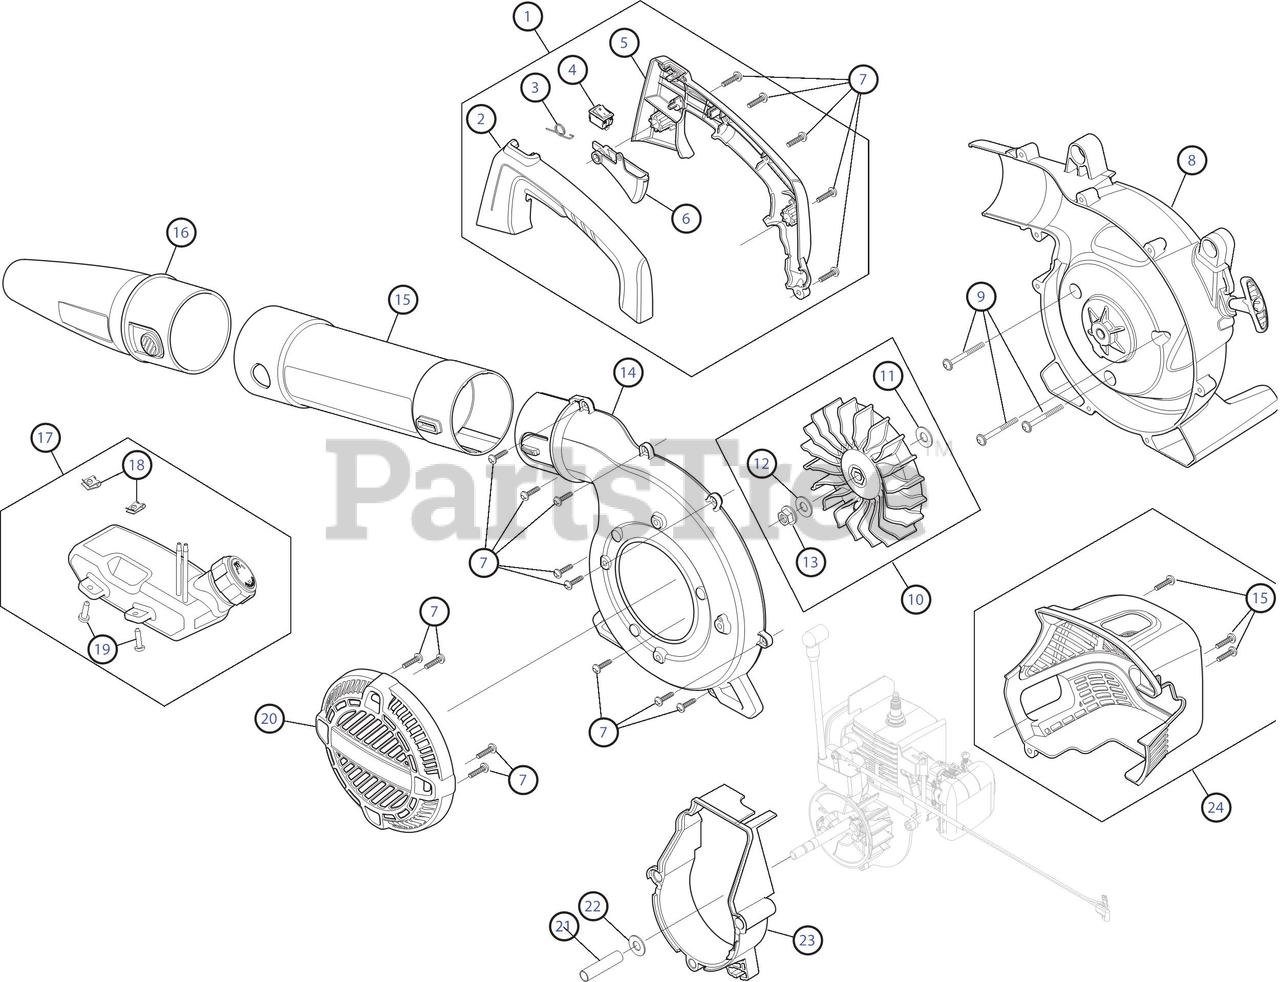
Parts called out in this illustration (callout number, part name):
1	Handle Assembly
2	Handle (LH)
3	Trigger Spring
4	On/Off Switch
5	Handle (RH)
6	Throttle Trigger
8	Impeller Housing Assembly (RH)
10	Impeller Assembly
11	Washer
12	Lock Washer
14	Impeller Housing Assembly (LH) (Incl. 7)
15	Upper Blower Tube
16	Blower Nozzle
17	Fuel Tank Assembly
18	U-Shaped Nut
20	Intake Cover (Incl. 7)
21	Shaft Spacer
22	Washer
23	Engine Adapter (Incl. 9)
24	Engine Cover Housing (Incl. 7)
